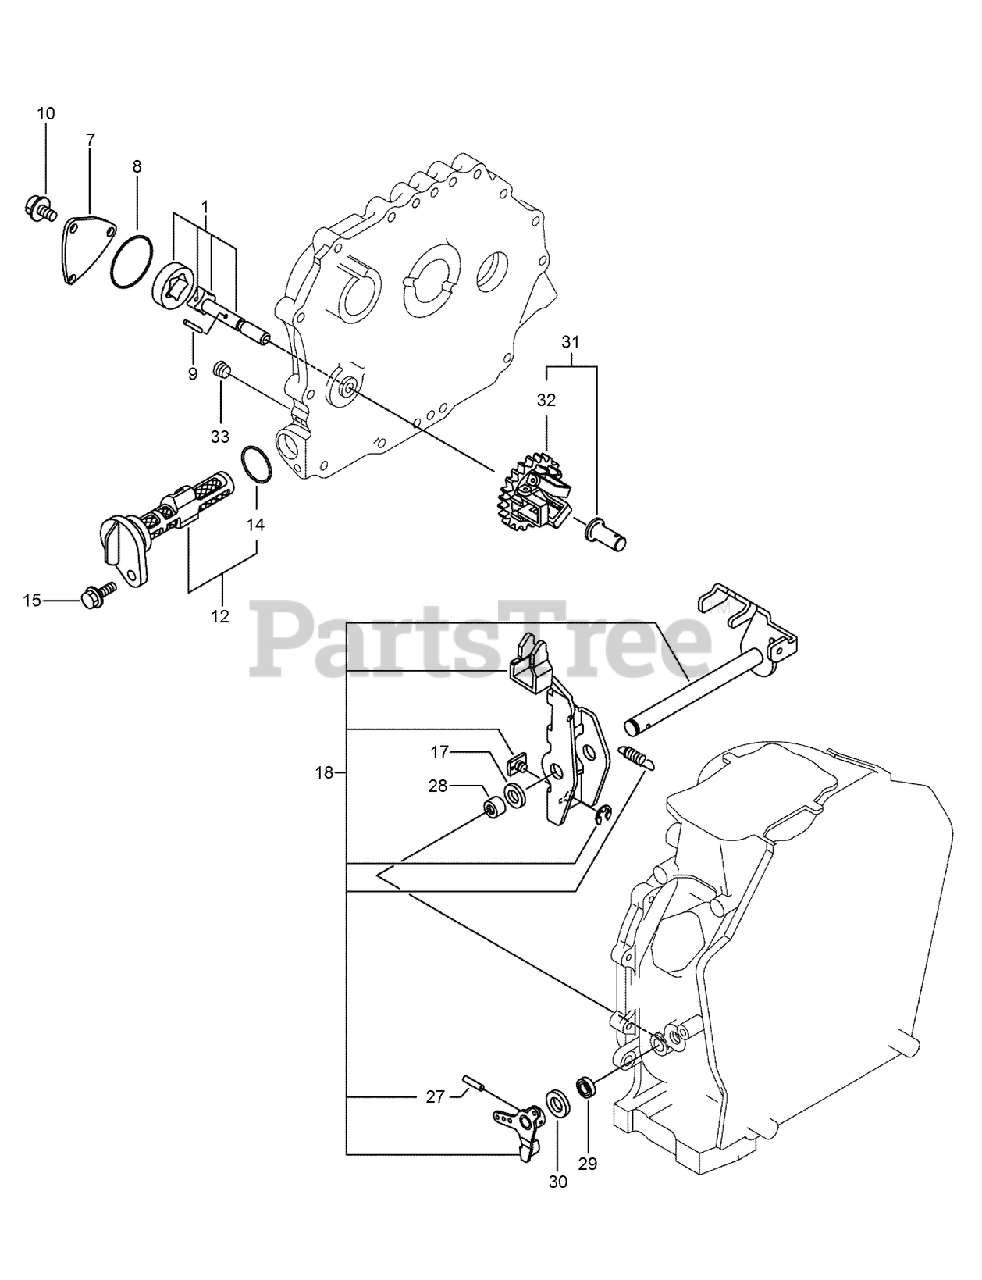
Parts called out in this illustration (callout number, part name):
1	OIL PUMP ASM
7	COVER-PUMP, OIL
8	O-RING
9	PIN-PARALLEL
12	OIL FILTER ASM
14	O-RING
17	WASHER
18	GOVERNOR LEVER ASM
27	PIN-TAPER
28	BEARING-NEEDLE
29	SEAL-OIL
30	WASHER-THRUST
31	GOVERNOR ASM
32	GOVERNOR WEIGHT ASM
